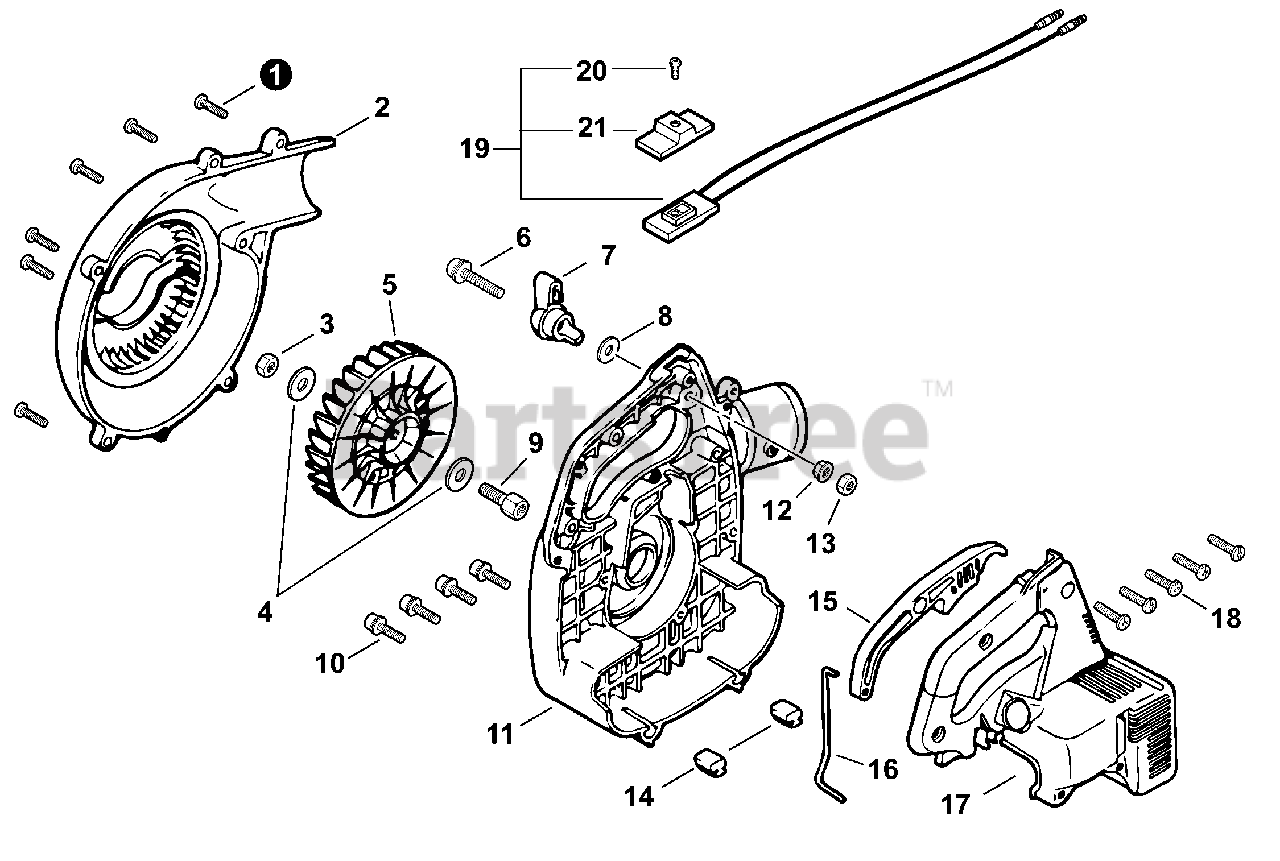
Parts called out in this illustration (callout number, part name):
1	SCREW 5×20
2	COVER, FAN
6	SCREW 5×25
7	LEVER, CRUISE CONTROL
8	WASHER 5.5×12×0.8
9	HUB, FAN
10	BOLT 4×22
11	CASE, FAN
12	NUT, FLANGE M5
15	TRIGGER, THROTTLE
16	ROD, THROTTLE
17	COVER, ENGINE
18	SCREW 5×20
19	SWITCH, ON-OFF
20	SCREW 3×10
21	KNOB, SWITCH - ORANGE
